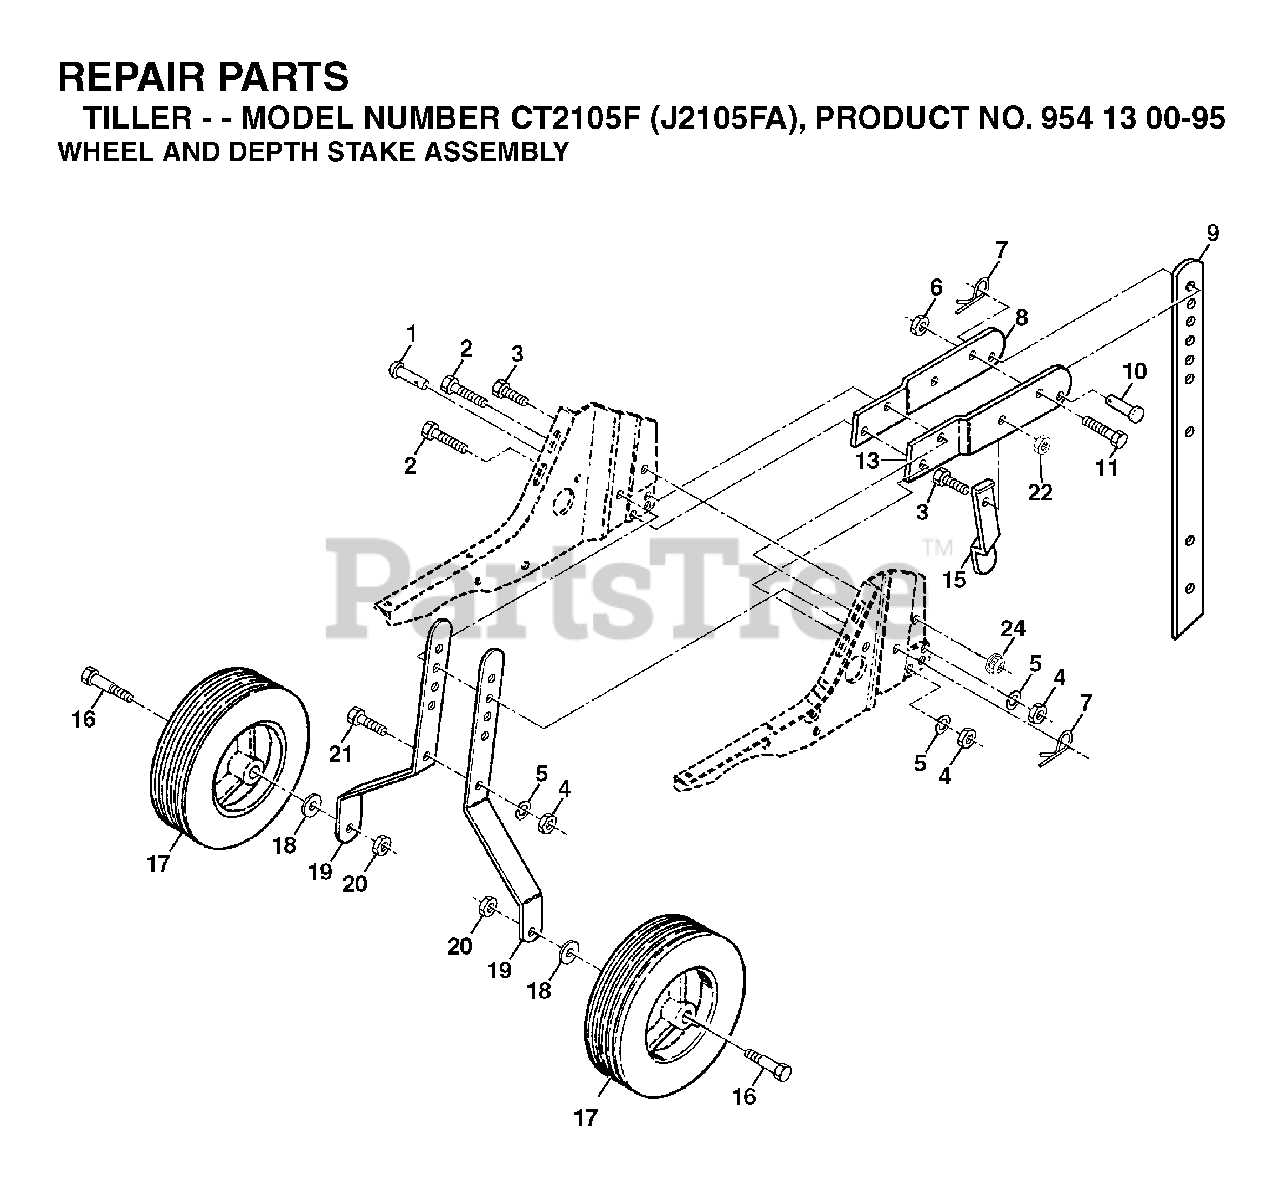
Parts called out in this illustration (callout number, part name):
1	PIN
2	BOLT
3	BOLT
5	LOCKWASHER
6	NUT
7	SPRING.RETAINER
8	SUPPORT.STAKE.RH.BLACK
9	RP STAKE.DEPTH.13.25.W/9HOLES
11	BOLT
16	BOLT.SHOULDER
18	WASHER
20	LOCKNUT
21	BOLT RB
22	NUT.71038.31-18.HEX.NYLOCK
24	LOCKNUT-FLANGE 5/16-18
